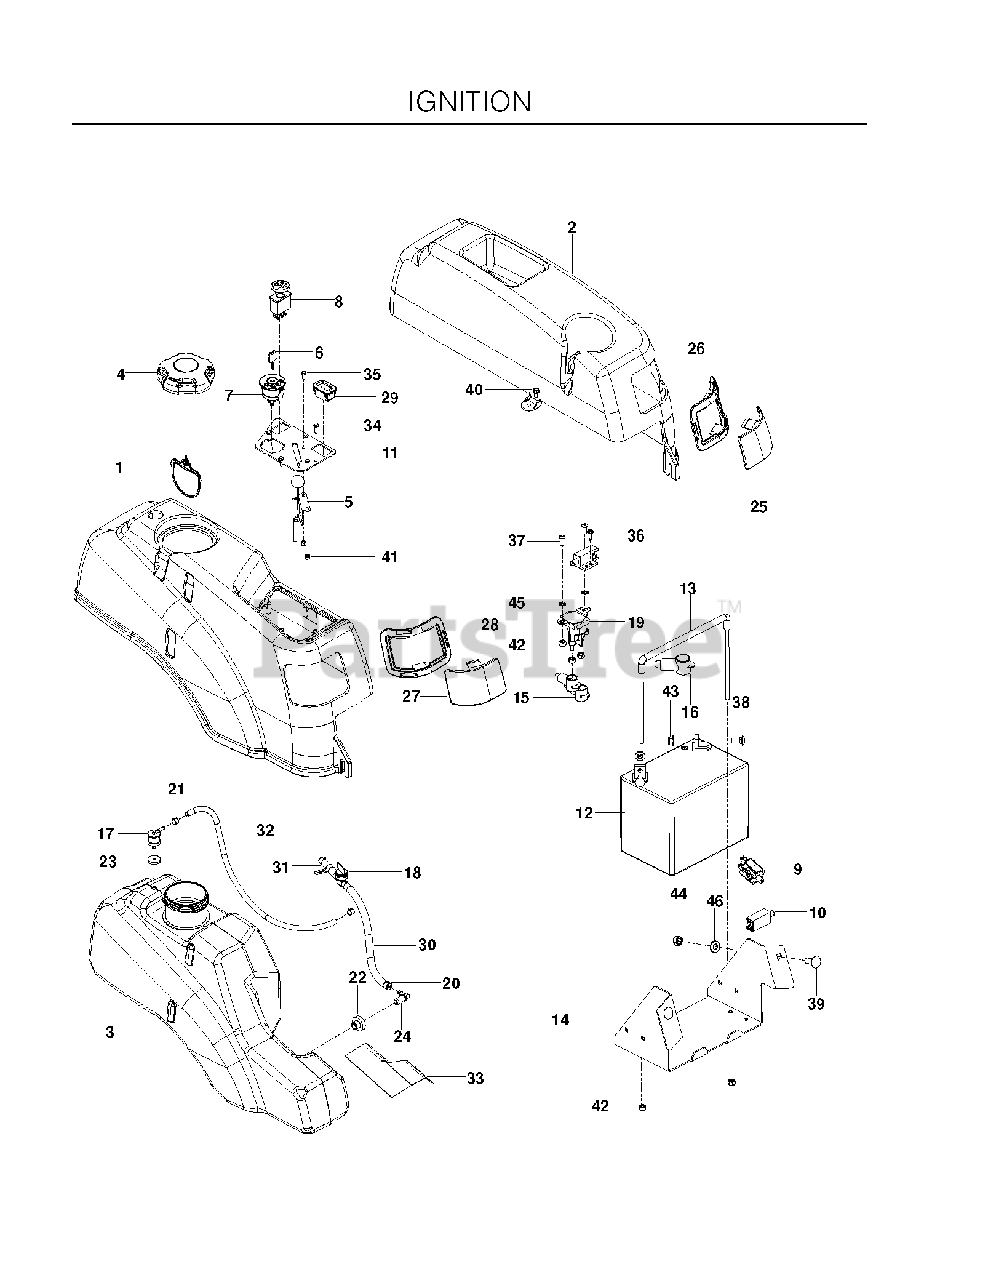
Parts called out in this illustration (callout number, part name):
3	TANK, FUEL, RT-EPA
4	CAP, FUEL
5	CABLE, THROTTLE
6	KEY
7	IGNITION SWITCH
8	SWITCH, BLADE
9	SWITCH, BRAKE 3P
10	SWITCH, INTERLOCK
12	BATTERY, 12 V 330 AMP TBR
13	BATTERY TIE DOWN ASSEMBLY
14	BOX, BATTERY, BLACK
15	TERMINAL COVER-SM
17	VALVE, FUEL CHECK
18	FUEL VALVE
19	SOLENOID
20	HOSE CLAMP
21	CLAMP, HOSE
22	RUBBER GROMMET
23	GROMMET, CHECK VALVE
29	HOUR METER
30	GAS LINE 10"
31	FUEL LINE 2.5"
32	HOSE, FUEL, 3/16" X 20"
34	SCR #10-12X3/4 HEX WAS HD ZD
35	HCS #10-24 X 1/2
36	SCREW #10 X 1/2 SELF TAPPING
37	SCR 1/4-20 X 5/8 BTN SKT HD ZD
38	BOLT 5/16C X 3/4" CARRIAGE
39	RHSNB 3/8C X 1
40	BOLT 1/4-20 X 1/2 HWST
41	NUT 10-24 NYLOC
42	NUT 1/4-20 NYLOC
43	5/16-18 NYLOC FLANGE NUT
44	NUT 3/8-16 NYLOC
45	WASHER 1/4 INT TOOTH
46	WASHER 3/8 SAE FLAT
